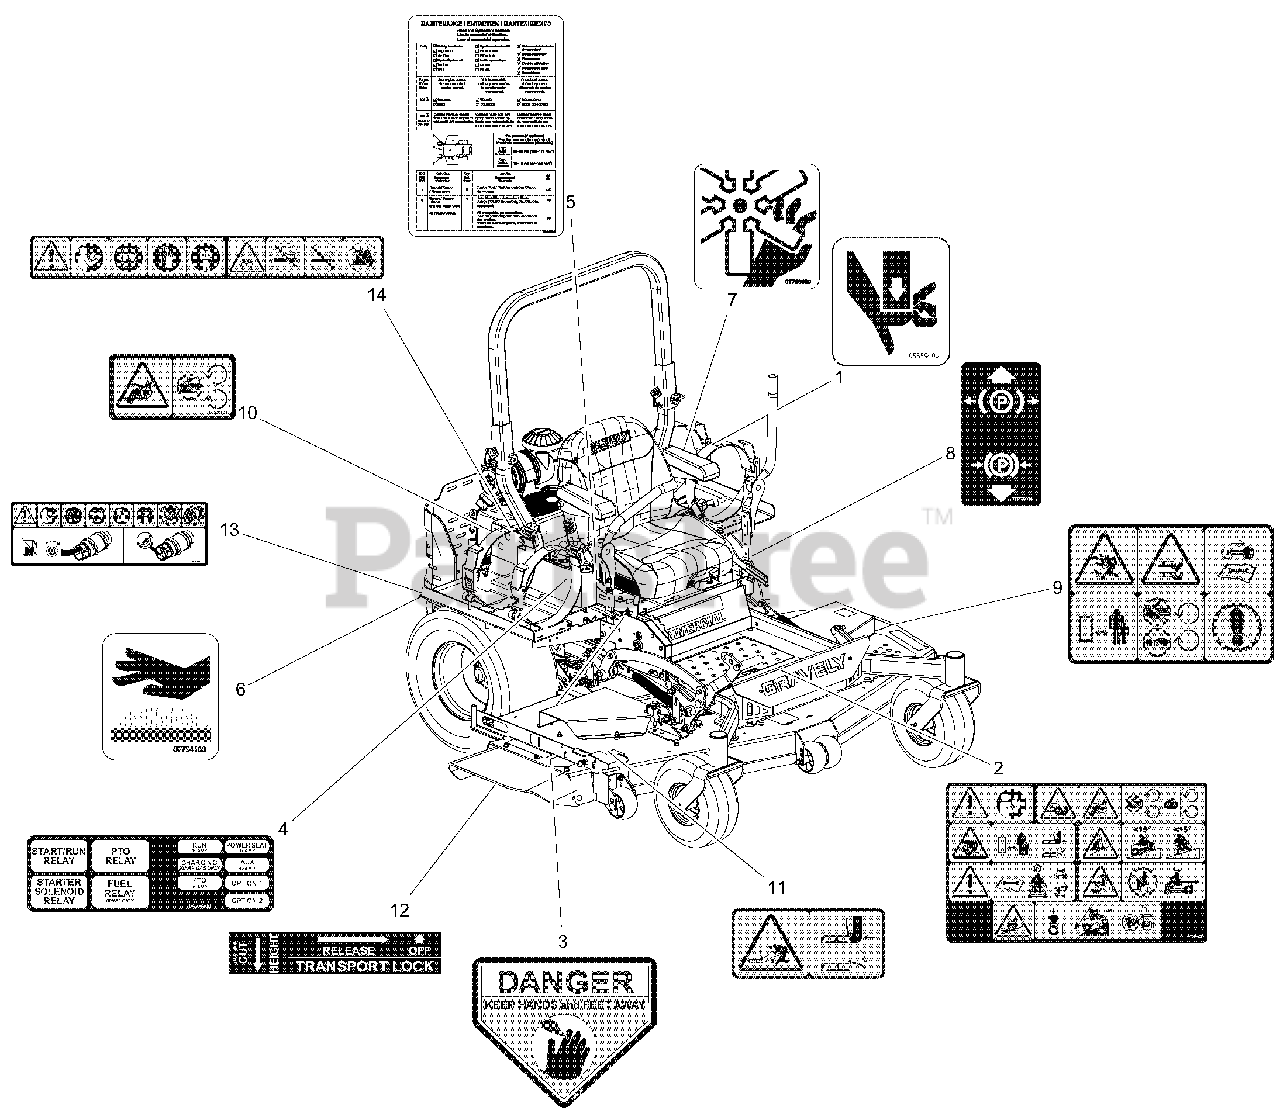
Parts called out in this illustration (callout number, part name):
1	DECAL, PINCH POINT
2	DECAL, MAIN SAFETY, COMMERCIAL
3	DECAL, DANGER
4	DECAL, FUSE BOX
5	DECAL, MAINTENANCE
6	DECAL HOT SURFACE
7	DECAL, DANGER - FAN
8	DECAL, PARKING BRAKE LEVER
9	DECAL, SAFETY - MOWER DECK
10	DECAL, SAFETY - GUARDING
11	DECAL, SAFETY - DECK GUARDING
12	DECAL, TRANSPORT LOCK INSTRUCT
13	DECAL, HORZ. MOWER TANKS ONLY
14	DECAL, SAFETY -LP
